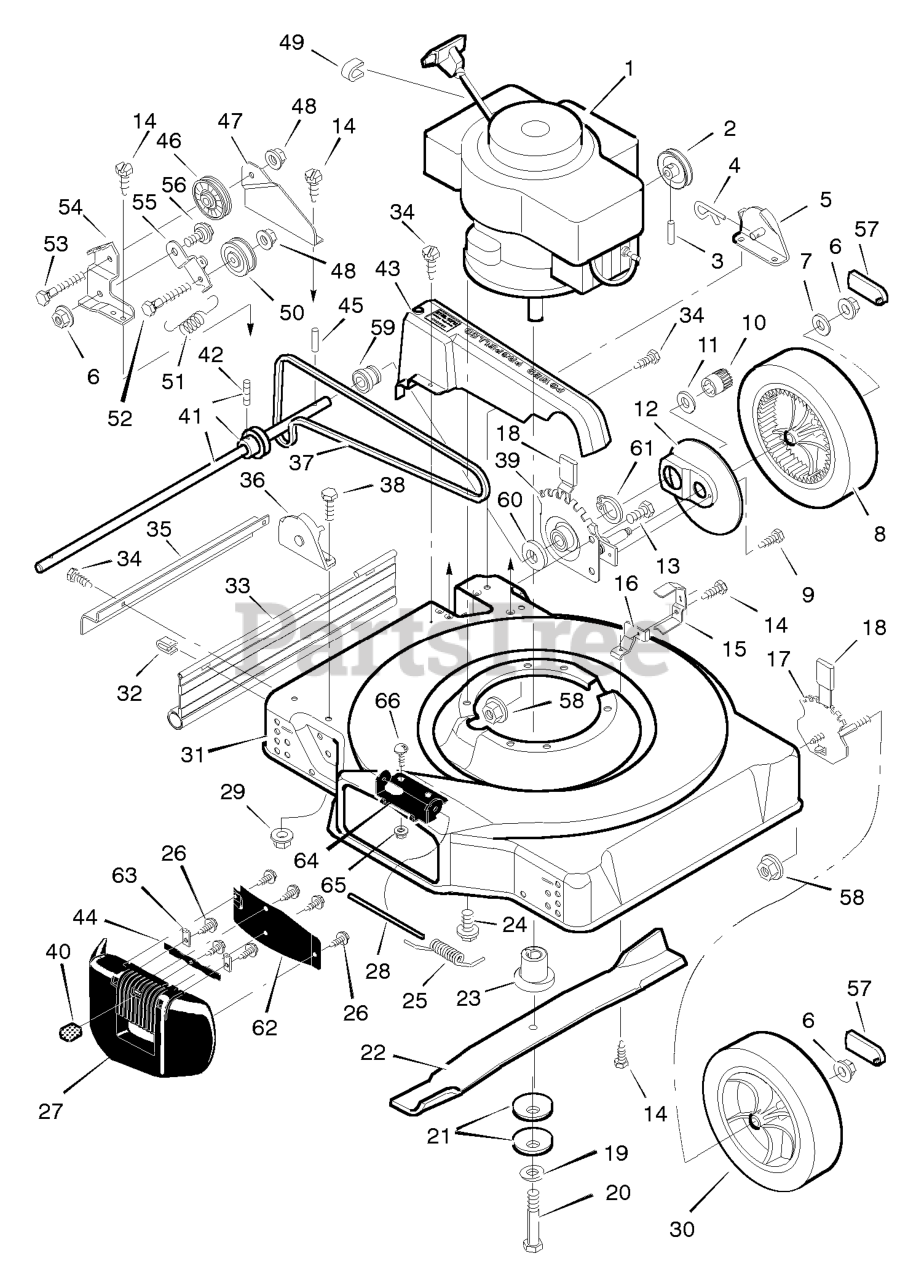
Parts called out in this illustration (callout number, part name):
1	Engine *
3	Pin, Spring
4	Pin, Hair
5	Bracket, Left Handle
6	Nut
7	Washer
8	Wheel, Drive
10	Gear, Right Pinion
12	Cover, Dust
13	Bolt, Hex
15	Guide, Belt
16	Belt Guide, Briggs
17	Height Adjuster, Front
21	Washer, Belleville
23	Adapter, Blade
24	Bolt, Engine
25	Spring, Torsion
27	Deflector, Chute
29	Nut
30	WHEEL & TIRE ASSEMBLY, White, 8"
31	Housing
32	Retainer
33	Deflector, Rear
35	Guard, Axle
36	Bracket, Right Handle
37	Belt, Briggs & Stratton
39	Height Adjuster, Left
40	Knob, Latch
41	Axle, Pulley & Setscrew
42	Setscrew
43	Belt Guard, Briggs
44	Latch, Lock
45	Pin, Drive
46	Pulley, Idler
47	Support, Idler
48	Nut
49	Stop, Rope
50	Pulley, Idler
51	Spring, Extension
52	Bolt, Hex
53	Bolt, Hex
54	Bracket, Idler
55	Arm, Idler
56	Bolt, Shoulder
57	Cap, Hub
58	Nut, Flange
59	Bearing and Retainer
60	Washer, Belleville
61	Retainer Ring
63	Retainer
64	Bracket, Deflector
65	Locknut, Flange
66	Bolt, Carriage
